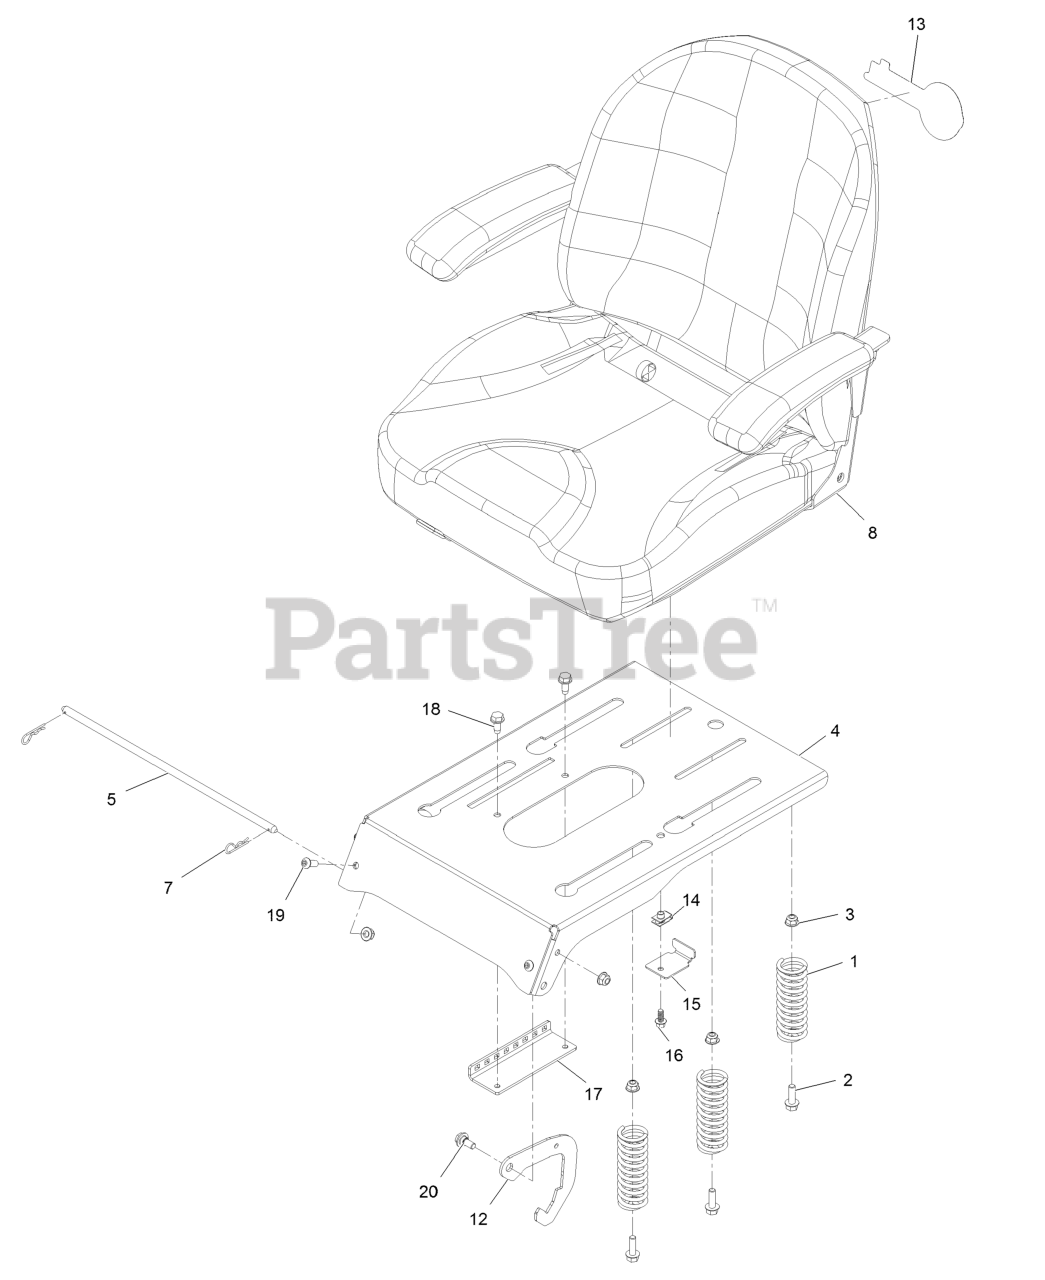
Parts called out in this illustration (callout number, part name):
1	Spring-Compression
2	Screw-HH Flg 5/16-18 X 1
3	Nut-Nyloc 5/16-18 Flg
4	Pan-Seat, Deluxe
5	Rod-Pivot, Narrow
7	Pin-Cotter
8	Seat ASM, Exmark
12	Latch-Seat
13	Decal, Exmark Logo
14	Nut-Retainer-Panel 1/4-20
15	Bracket-Stop, Seat
16	Screw-HH 1/4-20 X 5/8
17	Bracket-Latch, Seat
18	Screw-HWH 5/16-18 X 3/4 Tf
19	Screw-Button Head 5/16-18 X 3/4
20	Screw-Shoulder
